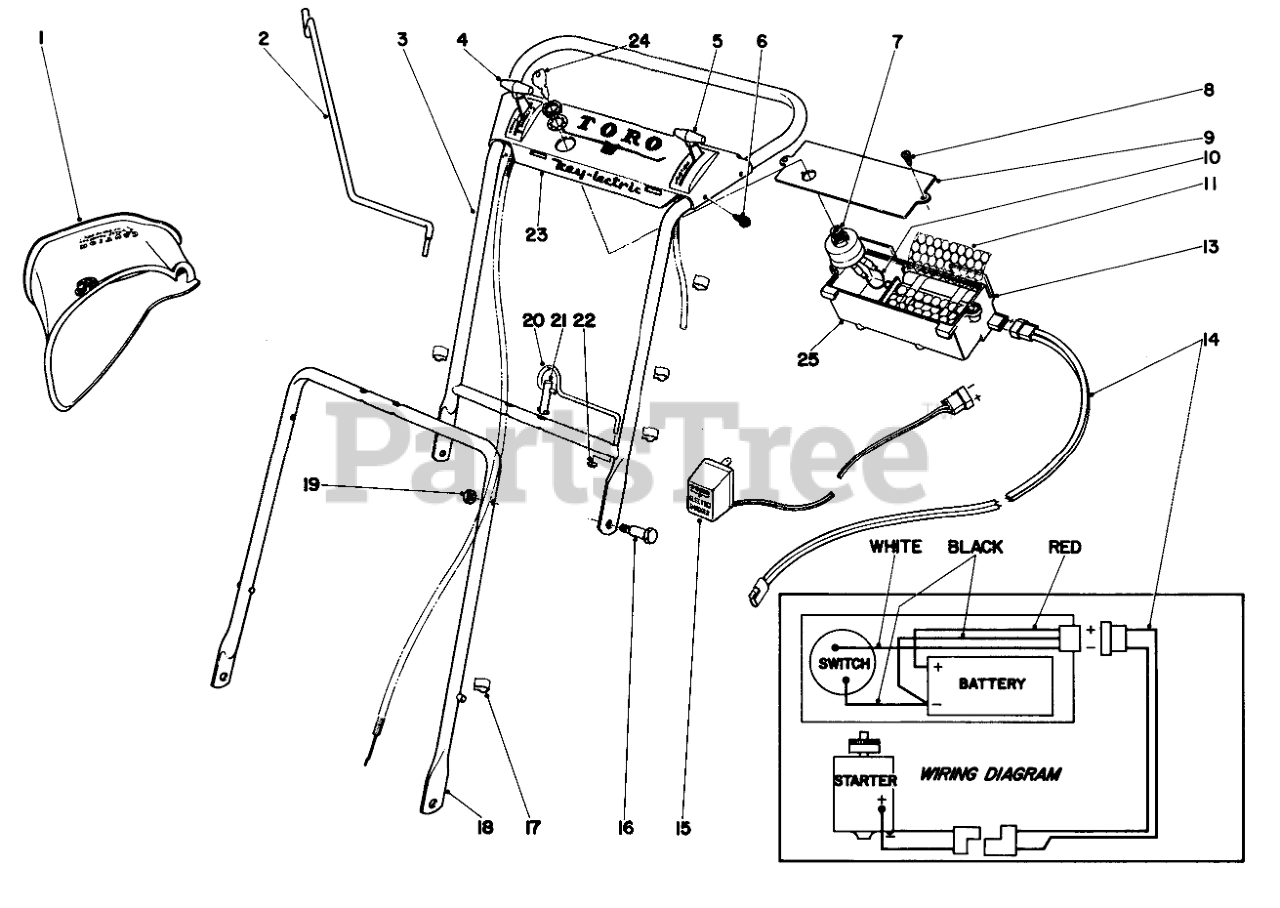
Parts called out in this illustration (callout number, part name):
1	Attachment Bag
2	GRASS BAG HANGER
3	Handle-Upper
4	Throttle Control
5	Traction Control
6	Self Tapping Screw
7	Switch, Starter
8	Self Tapping Screw
9	Cover, Battery Pack
10	Lead Wire
11	Spacer-Battery
13	Container Battery Pack
14	Harness
15	Battery Charger
15	Charger, Battery (Canadian)
16	Screw
17	CONTROL WIRE CLIP
18	Handle-Lower
19	Nut
20	Pin, Latch
21	Pin, Latch
23	Escutcheon Plate
24	Key
25	Battery Pack Assy. (Incl. Ref. 10-13)
